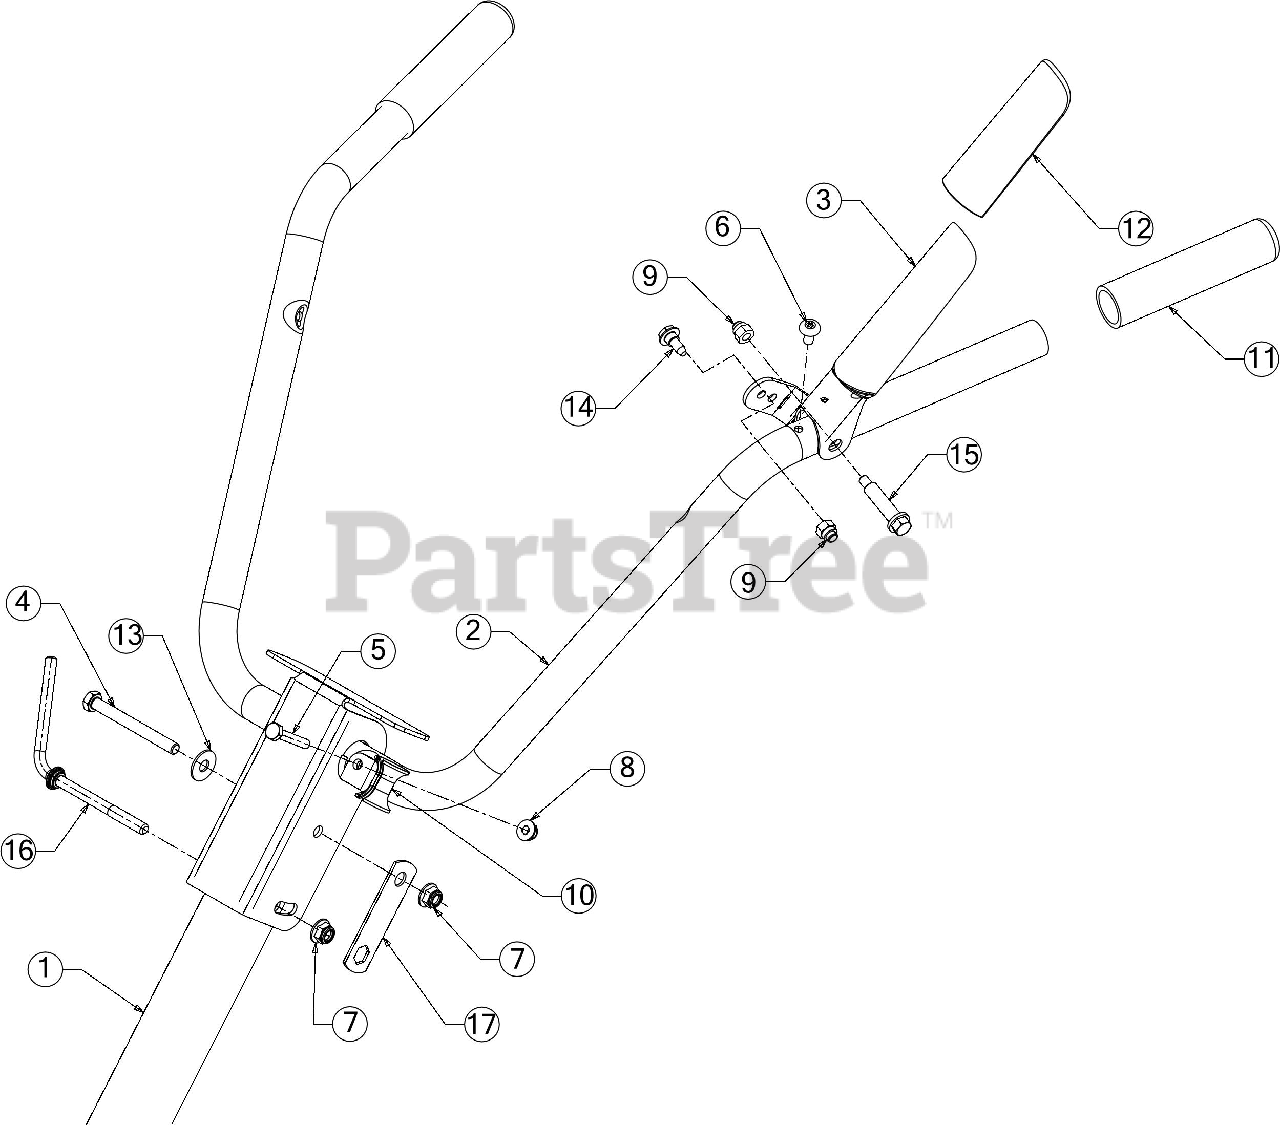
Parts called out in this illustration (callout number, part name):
1	HANDLE TUBE ASSEMBLY
2	HANDLE ASSEMBLY
3	CLUTCH LEVER ASSEMBLY
4	HEX SCREW 5/16-18 X 3.00
5	SCREW 1/4-20 X 1.50 GR.5
6	SCREW 1/4-14 X .625
7	FLANGE LOCK NUT 5/16-18
8	FLANGE LOCK NUT
9	HEX ACORN NUT
10	ROPE GUIDE
13	BELL WASHER .337 X.867 X .057
14	SHOULDER SCREW
15	SHOULDER SCREW
16	CRANK ADJUST HANDLE
17	RETAINING HEX BRACKET
